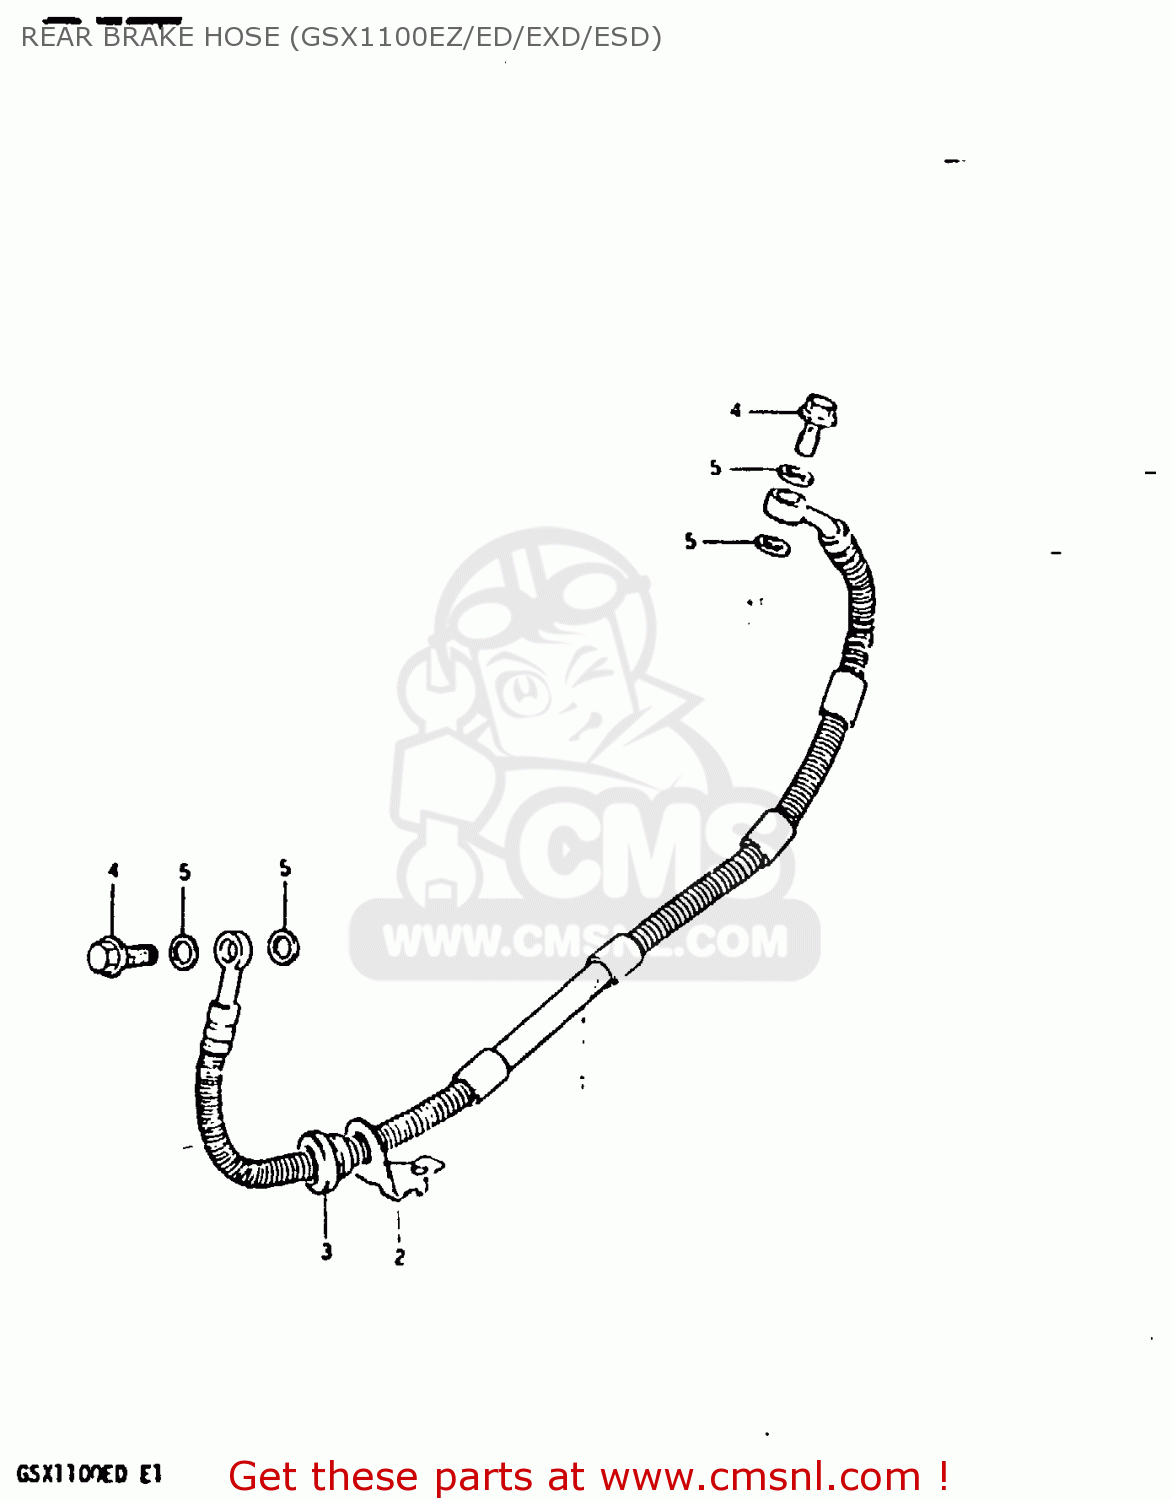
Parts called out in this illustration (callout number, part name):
1	HOSE,REAR BRAKE
2	GUIDE,BRAKE HOSE
3	GROMMET,BRAKE HOSE GUIDE
4	BOLT,UNION
5	WASHER
